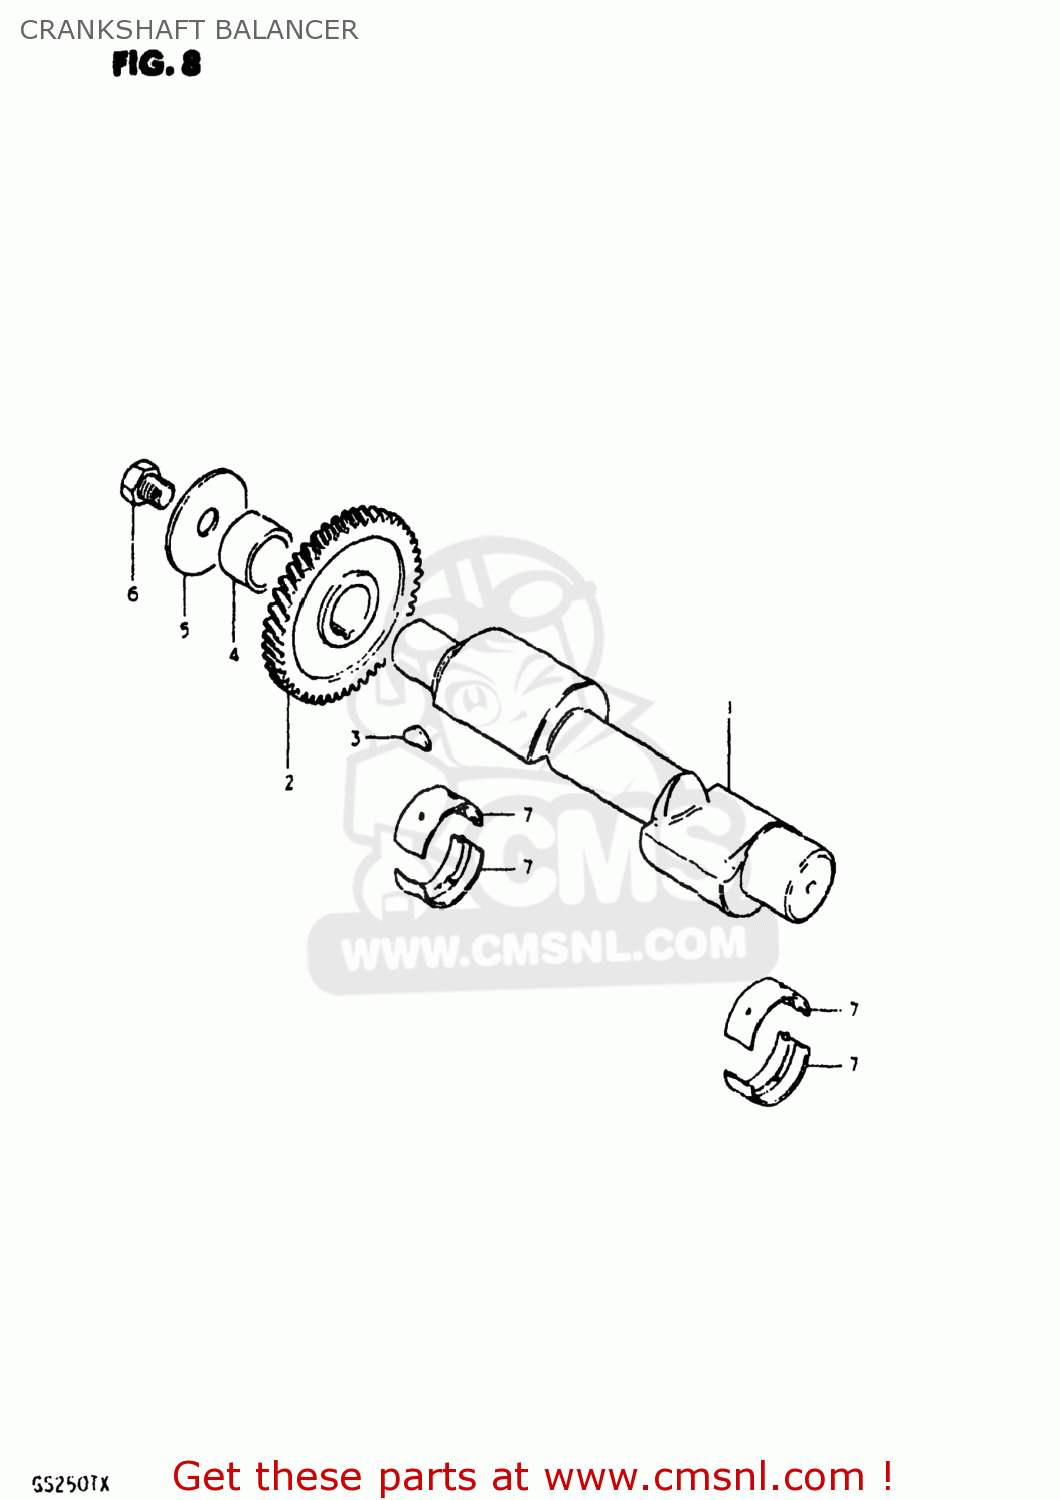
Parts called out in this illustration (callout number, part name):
1	BALANCER,CRANKSHAFT
2	GEAR,CRANK BALANCER
3	KEY 4MM
4	SPACER
5	WASHER(12X50X3)
6	BOLT
7	METAL CRANKSHAFT (BROWN)
